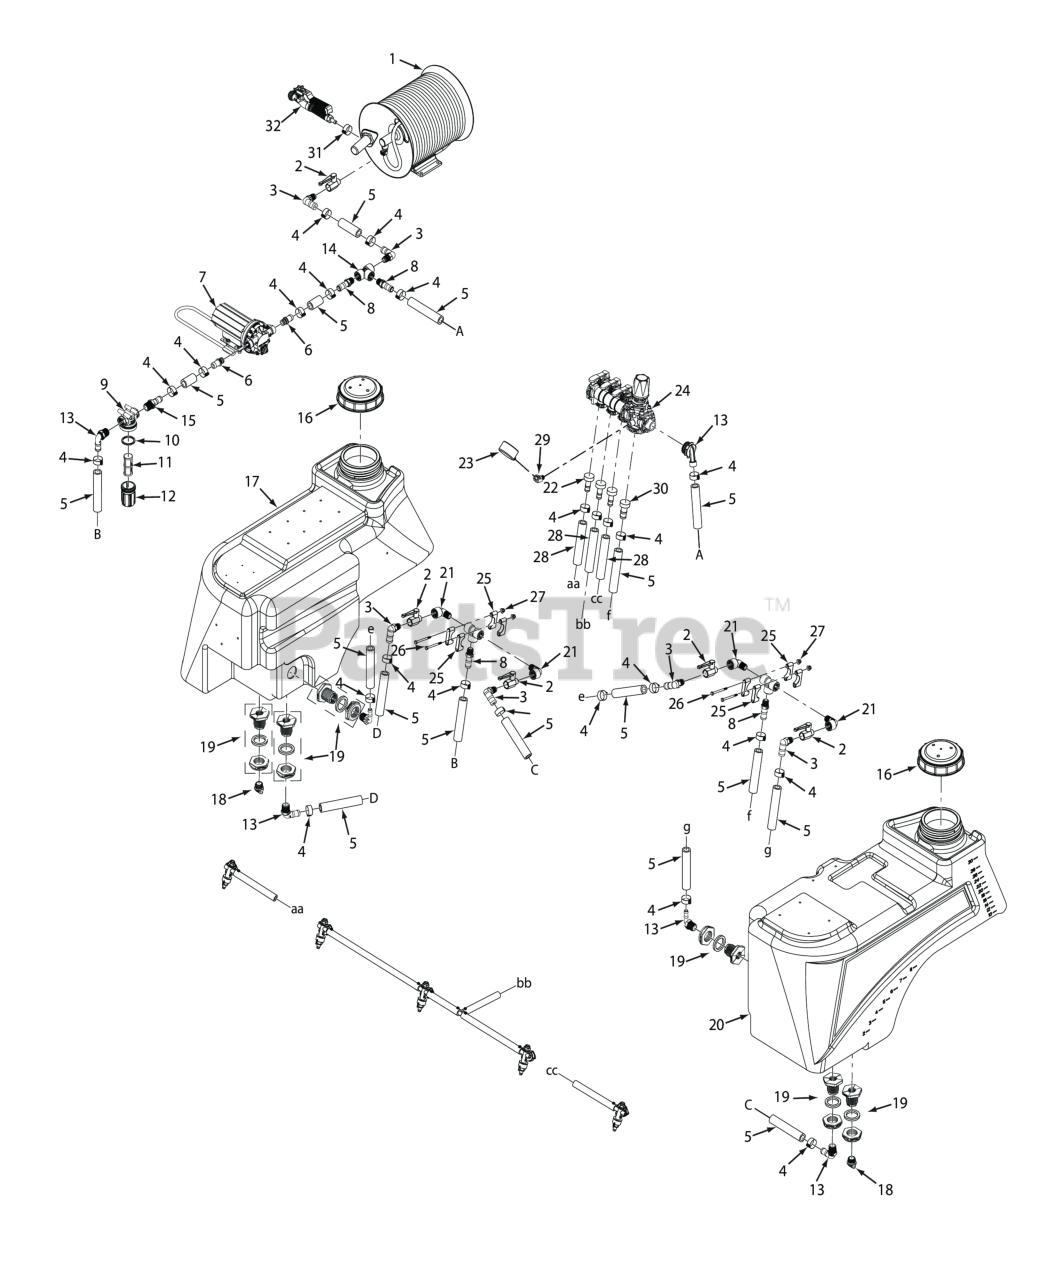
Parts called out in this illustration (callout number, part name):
1	Hose Reel Assy
2	Valve, Ball 1/2" NPT
3	Fitting, 90 Deg.1/2 - 14 NPT X 3/4" Hose
4	CLAMP, WORM DRIVE
5	Hose, 3/4" EPDM ( Order by the inch)
6	Fitting, 3/4" O-ring
7	Pump, 12V Electric
8	Hose Barb, 1/2" NPT X 3/4" Hose
9	Strainer Head
10	Gasket
11	Screen
13	Fitting, 90 Deg. 3/4 - 14 NPT x 3/4" Hose
14	Tee Fitting, 1/2 NPT
15	Hose Barb, 3/4 NPT x 3/4" Hose
16	Cap, Sprayer
17	Tank Assy, RH
18	Drain Plug, 3/4"
19	Fitting, 3/4" NPT
20	Tank Assy, LH
21	Fitting, Street Elbow 90 Deg. 1/2"
22	Fitting, Valve
23	Pressure Gauge
24	Valve Assy (Incl.
25	Mounting Bracket, Valve Assy
26	Bolt, 1/4 - 20 x 2.75 - Stainless Steel
27	Locknut, 1/4 - 20 Flg. Elastic Stop - Stainless Steel
28	Hose, 1/2" EPDM (order by the inch)
29	Fitting, 45 Degree 1/4 NPT
30	Fitting, Valve
31	Clamp, .69" Max. / .25" Min. Dia.
32	Sprayer Gun
